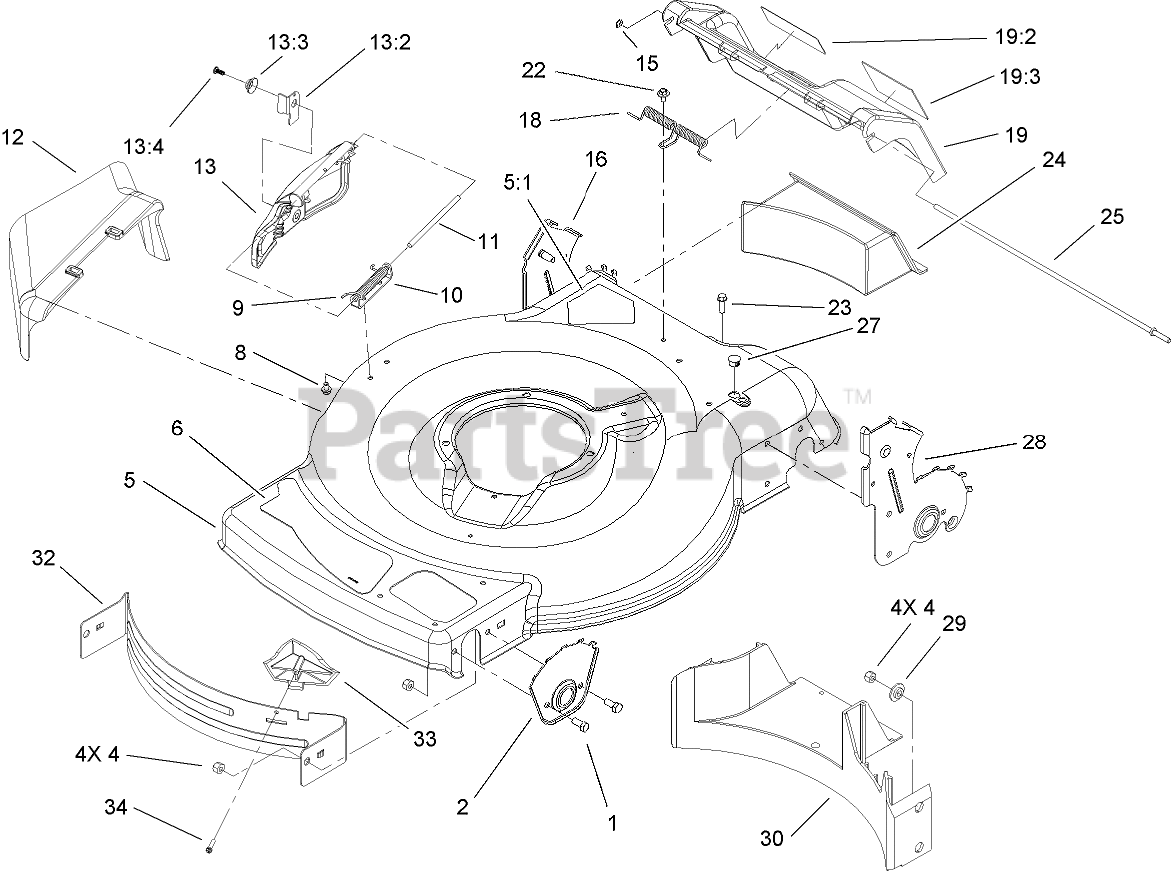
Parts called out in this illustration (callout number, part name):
1	SCREW-HH
2	Plate-HOC, Front
4	NUT-LOCK, NI
5	HOUSING
5:1	DECAL-DANGER
6	Decal-Deck
8	SCREW-HWH
9	SPRING-TORSION
10	BRACKET-COVER
11	ROD-COVER
12	CHUTE-DISCHARGE, SIDE
13	DISCHARGE DOOR ASM
13:2	LATCH-DOOR
13:3	CAP-DOOR
13:4	SCREW-PLASTITE
15	NUT-PUSH
16	8 INCH RH HOC PLATE ASM
18	Spring-Door, Rear
19	REAR DOOR ASM
19:2	DECAL-WARNING
19:3	DECAL-WARNING
22	SCREW AND WASHER ASM
23	SCREW-HWH
24	Plug-Discharge, Rear
25	Rod-Pivot, Rear Door
27	Plug-Dome
28	8 INCH LH HOC PLATE ASM
29	Washer-Stepped
30	Baffle-Rear
32	BAFFLE-FRONT
33	KICKER-FRONT
34	SCREW-PPH
